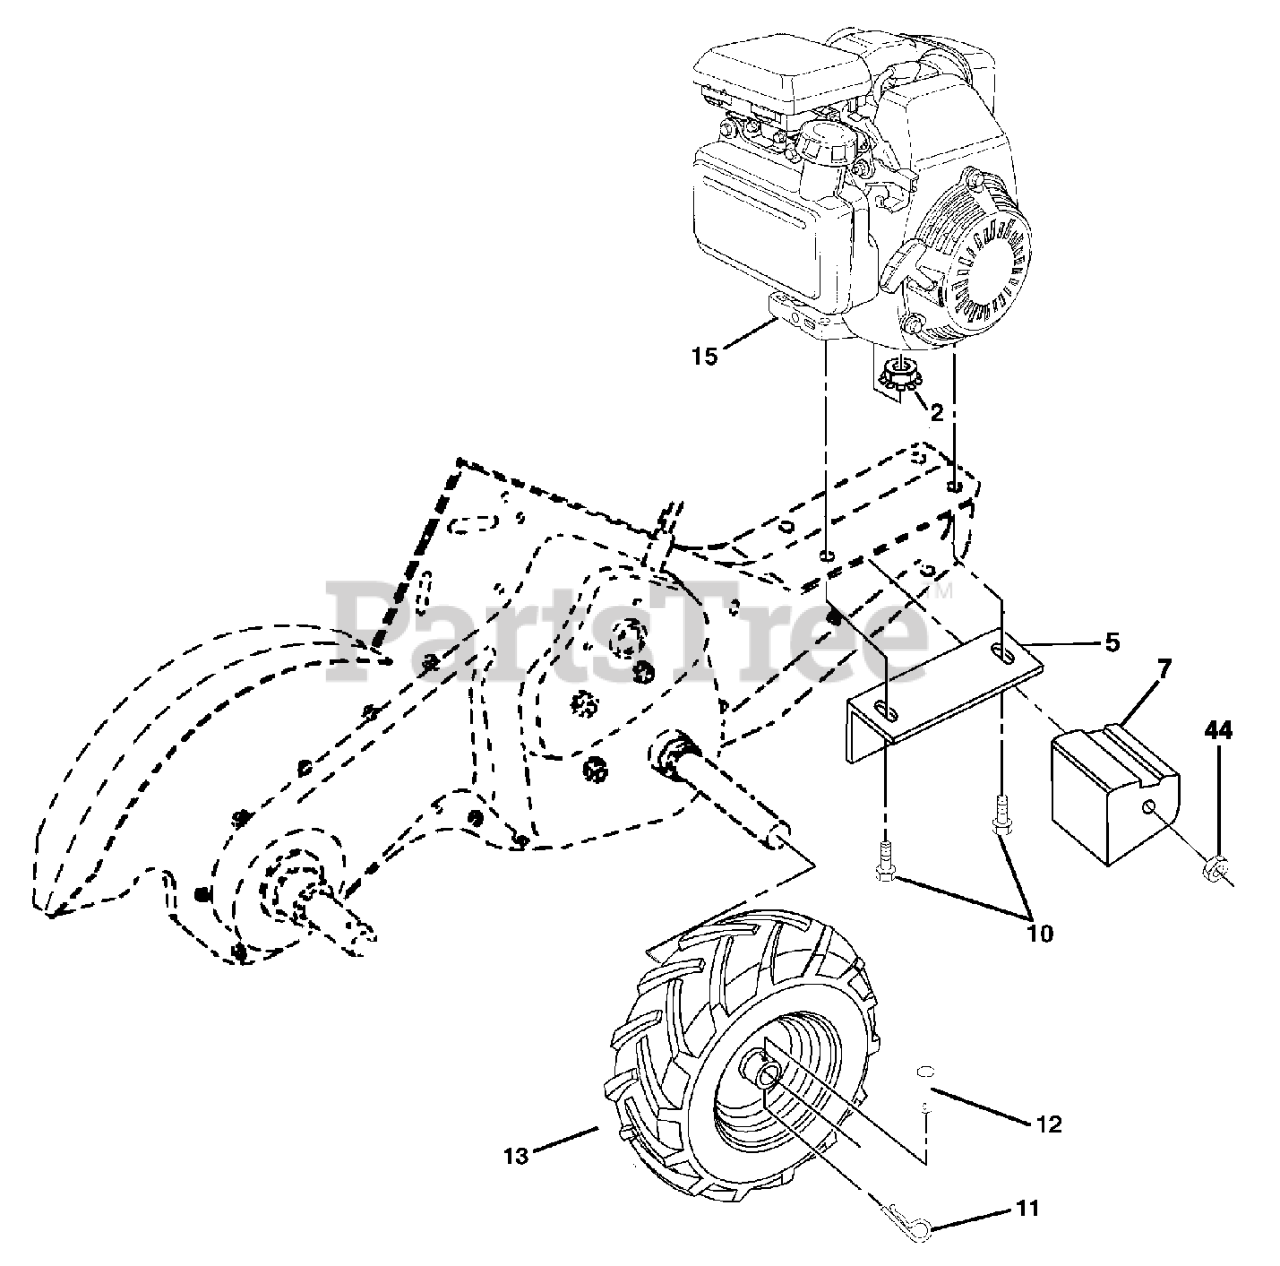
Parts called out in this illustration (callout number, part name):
2	LOCKNUT-FLANGE 5/16-18
5	BRACKET.REINFORCEMENT.RH.BLACK
7	COUNTERWEIGHT, RH
10	BOLT
11	RETAINER M
12	RIVET
13	WHEEL.DRT.RH.13X5X6.SILVER.KEN
